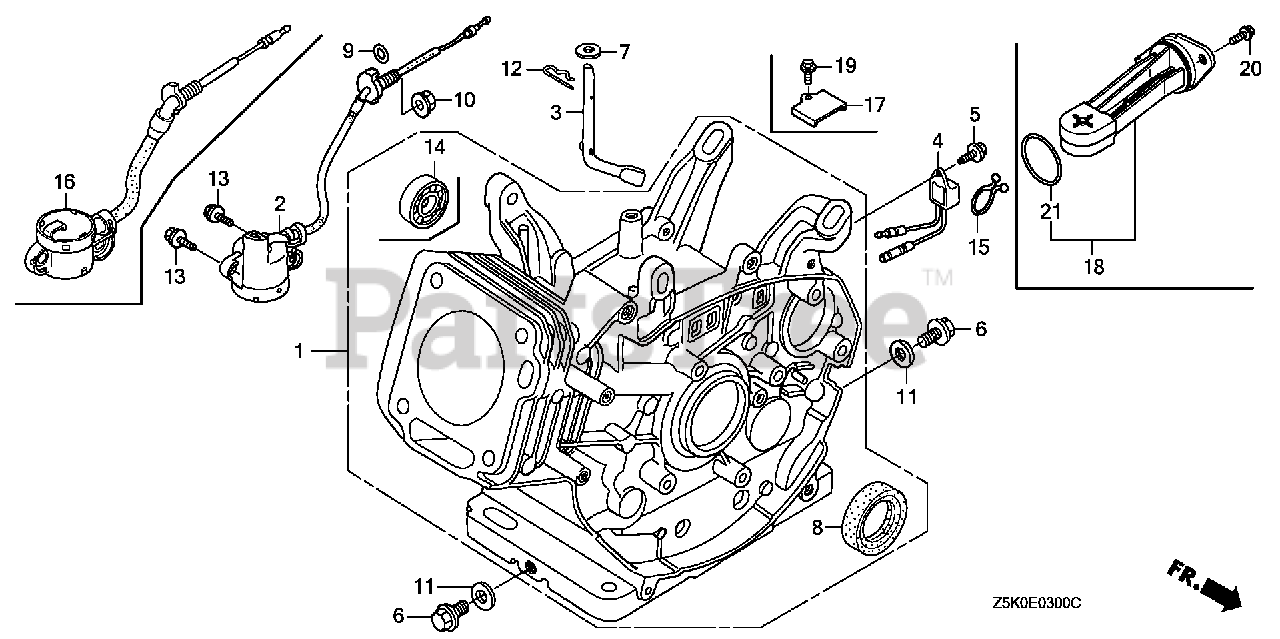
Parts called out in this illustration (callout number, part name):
1	CYLINDER ASSY. (BALANCER+ALERT)
3	SHAFT, GOVERNOR ARM
4	ALERT UNIT, OIL
5	BOLT, FLANGE (6X12) (CT200)
6	BOLT, DRAIN PLUG (12X15)
7	WASHER (8.2X17X0.8)
8	OIL SEAL (30X46X8) (NOK ASIA)
9	O-RING (13.5X1.5) (ARAI)
9	O-RING (14MM) (NOK)
10	NUT, FLANGE (10MM)
11	WASHER, DRAIN PLUG (12MM)
12	PIN, LOCK (10MM)
13	BOLT, FLANGE (6X12)
14	BEARING, RADIAL BALL (6202)
16	SWITCH ASSY., OIL LEVEL
